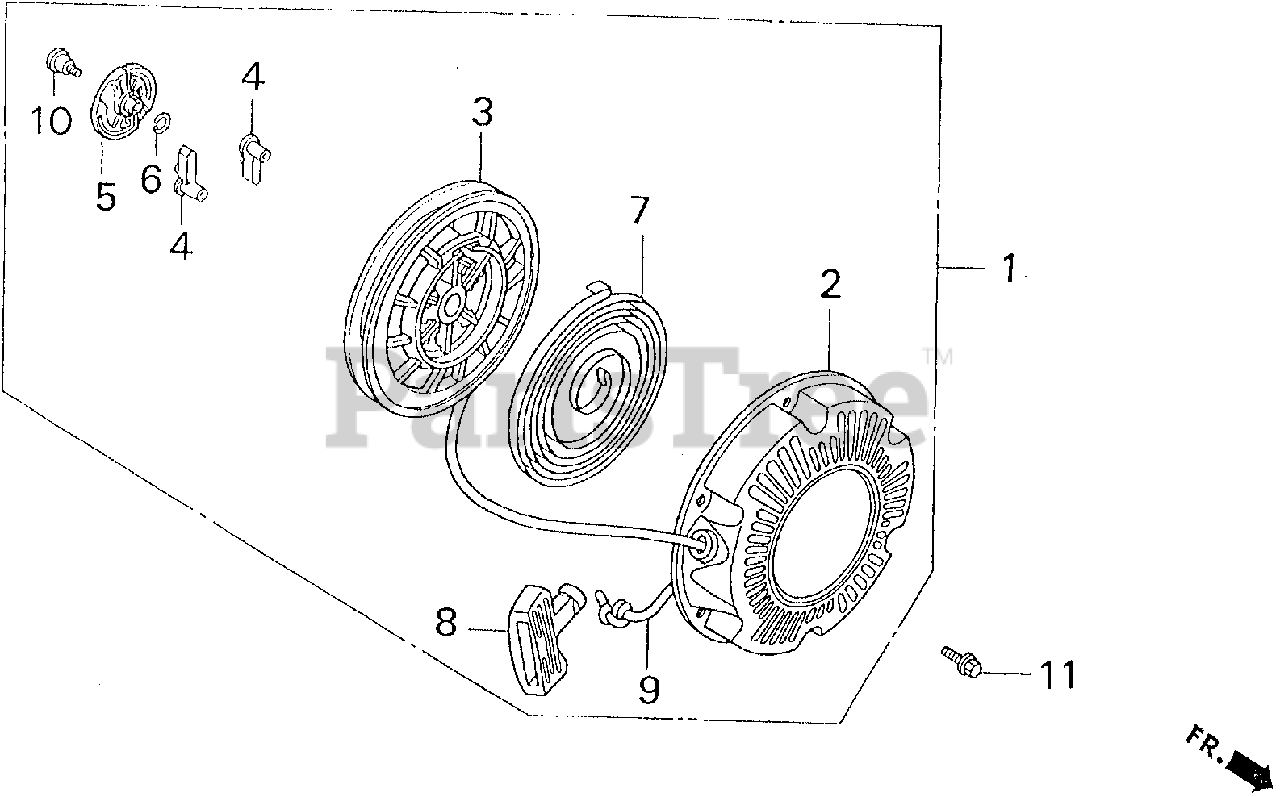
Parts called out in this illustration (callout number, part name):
1	STARTER ASSY., RECOIL *R8* (BRIGHT RED)
2	CASE, RECOIL STARTER *R8* (BRIGHT RED)
3	REEL, RECOIL STARTER
4	RATCHET, STARTER
5	GUIDE, RATCHET
6	SPRING, FRICTION
7	SPRING, RECOIL STARTER
8	GRIP, STARTER
9	ROPE, RECOIL STARTER
10	SCREW, SETTING
11	BOLT, FLANGE (6X8)
